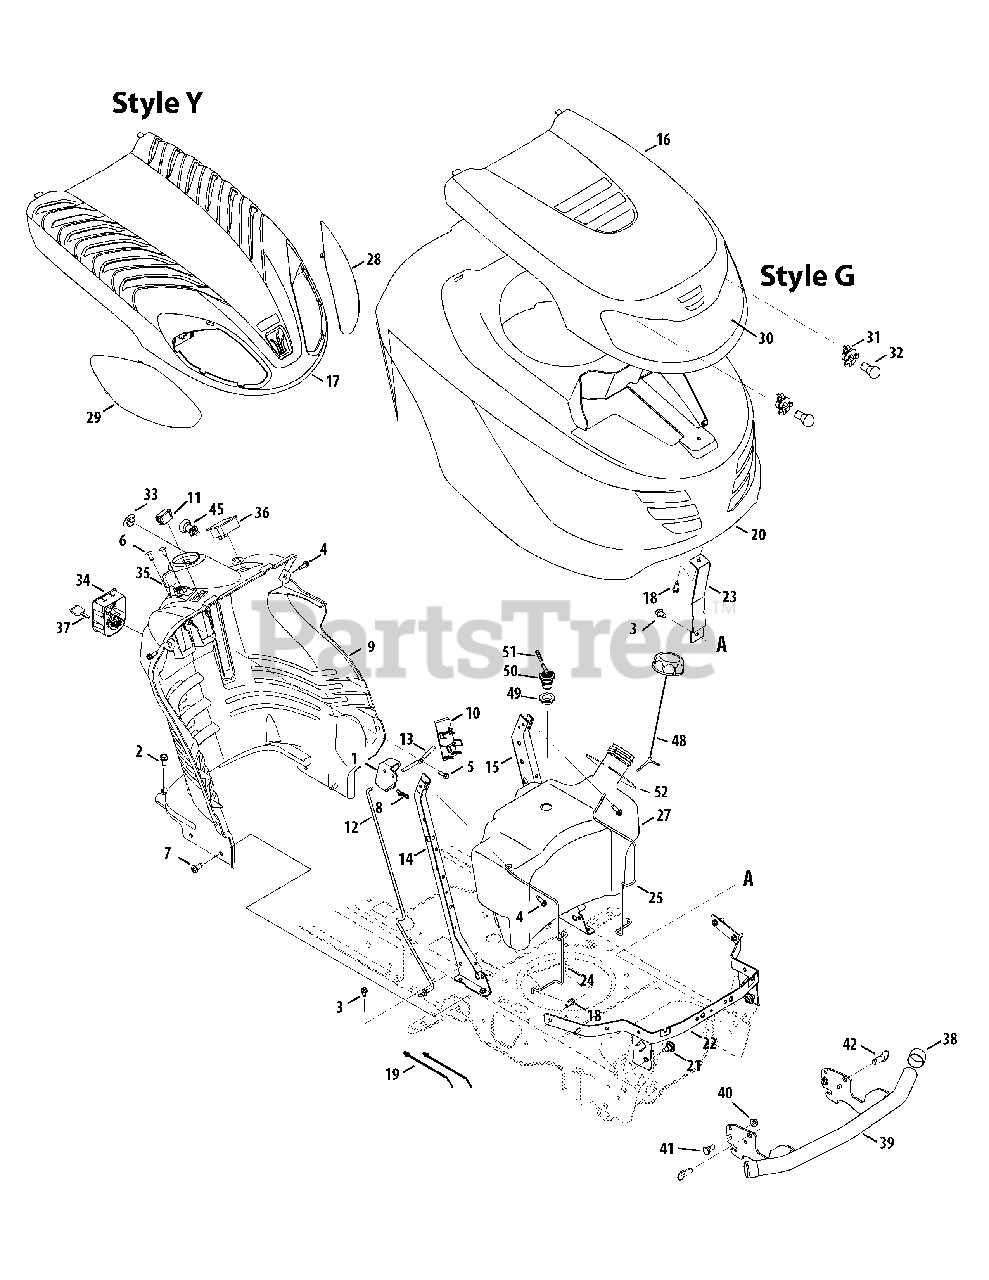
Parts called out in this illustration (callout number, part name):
1	Dash Lever
2	S-Tapp Screw 5/16-18 x .75
3	Hex Wash S-Tapp Screw 1/4-20 x .50
4	TT Screw. 1/4-20 x .625 Lg.
5	Hex Tapp Screw 1/4 x .75" Lg.
6	Torx Mach. AB-Tapp Screw. 1/4-14 x .625 Lg
7	Screw 5/16-18 x .75
8	Bow-Tie Cotter Pin
9	Dash Panel (Elect. PTO w/ fuel level window)
10	Cruise Cover Y/G Style
11	Light Switch Cap
12	Latch Control Rod
13	Pivot Rod
14	RH Dash Support Plate
15	LH Dash Support Plate
16	Upper "G" Style Hood
17	Upper "Y" Style Hood
18	Screw, Bos, 1/4 Dia. x .75
19	Cable Tie
20	G Style Hood (w/side fill fuel tank)
21	Shoulder Screw .43 x .29, 5/16-18
22	Hood Pivot Bracket
23	Hood Support Bracket
24	Tank Support Rod RH
25	Tank Support Rod LH
27	Fuel Tank 2.75 Gal. (side fill)
28	Lens LH - Style "Y"
29	Lens RH - Style "Y"
30	Lens (Style G)
30	Reflector Label
31	Socket
32	Miniature Lamp 12V Socket Type
33	Choke Plug
34	Key Switch Module
35	Throttle/Choke Cont. Cable 46.5" Lg.(Twin)
36	Ammeter
37	Ignition Key w/Plastic Cover
38	Bumper Cap
39	Bumper Assembly
40	Hex Lock-Nut 3/8-16 Nylon
41	Shoulder Screw. .498 x .340: 3/8-16
42	Quick Pin 1/2" dia. x 0.50
45	Electric PTO Switch
48	Cap-Fuel
49	Rubber Grommet
50	Roll over Valve
51	Hose Vent
52	Fuel Gas ket
